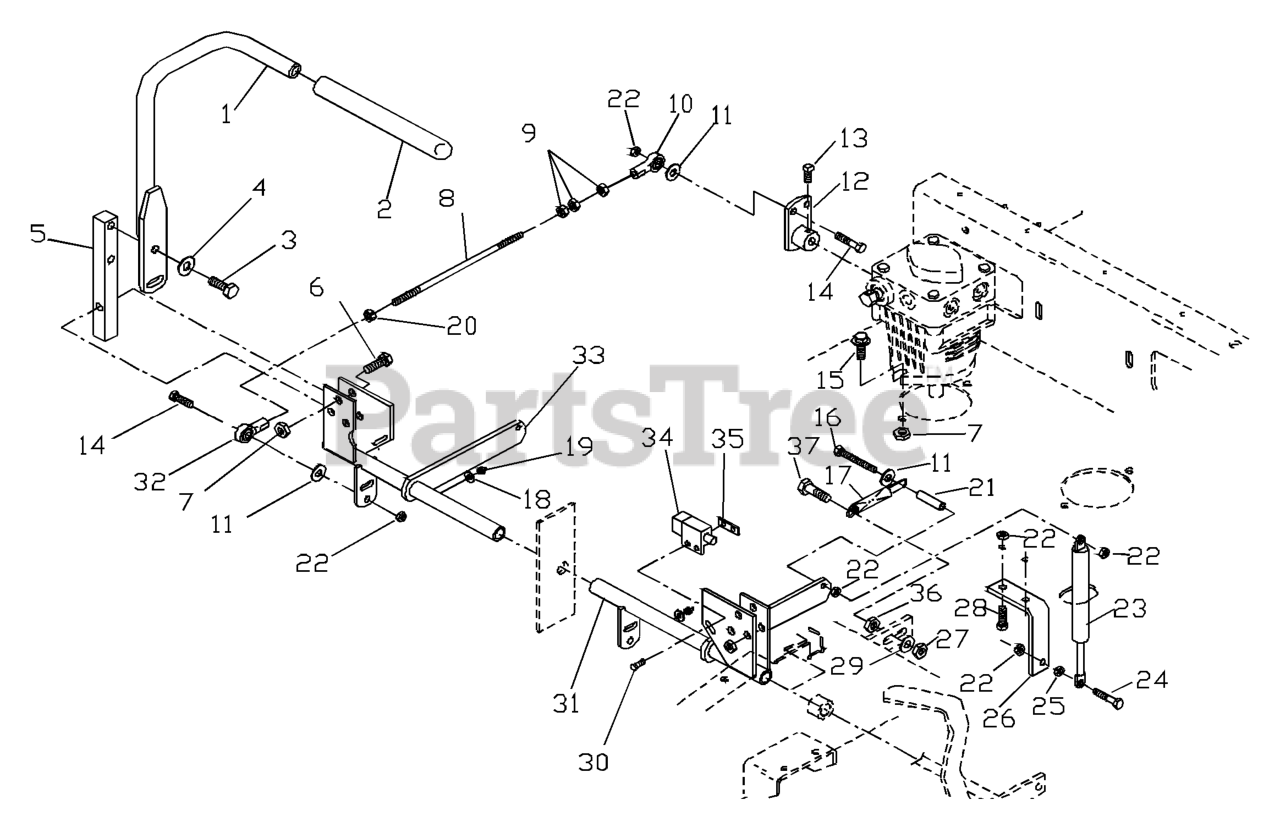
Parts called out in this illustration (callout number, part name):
1	CONTROL LEVER WELDMENT
3	HCS 3/8-16X1.GRD.5.ZD
4	WASHER, 3/8 DISC SPRING SPEC
5	CONTROL ARM
6	HCS 3/8C X 1 1/2
7	NUT 3/8C CENTERBLOCK
8	PUMP CONTROL LINK
10	BALL JOINT, RIGHT HANDED
11	WASHER 5/16 FLAT
12	PUMP LEVER
13	5/16C X 5/8 "V" POINT
14	HCS 5/16C X 1
15	4CS 3/8C X 1 SERRATED HEAD
16	TAP BOLT 5/16C X 2 1/4
19	ZERK
20	NUT 5/16F LEFTHAND
22	NUT 5/16C CENTERLOCK
24	HCS 5/16C X 1 1/4
25	NUT 5/16C WHIZ
26	BRACKET "I"
27	NUT 3/8-16 NYLOC
28	HCS 5/16C X 3/4
29	WASHER 3/8 FLAT
30	SCREW #10-24 X 5/8
31	CONTROL WELDMENT LT
32	BALL JOINT, LEFT HANDED
33	CONTROL WELDMENT RT.
34	SWITCH, INTERLOCK
35	TAPPED PLATE
36	NUT 3/8C WHIZ
37	HCS 3/8C X 2
